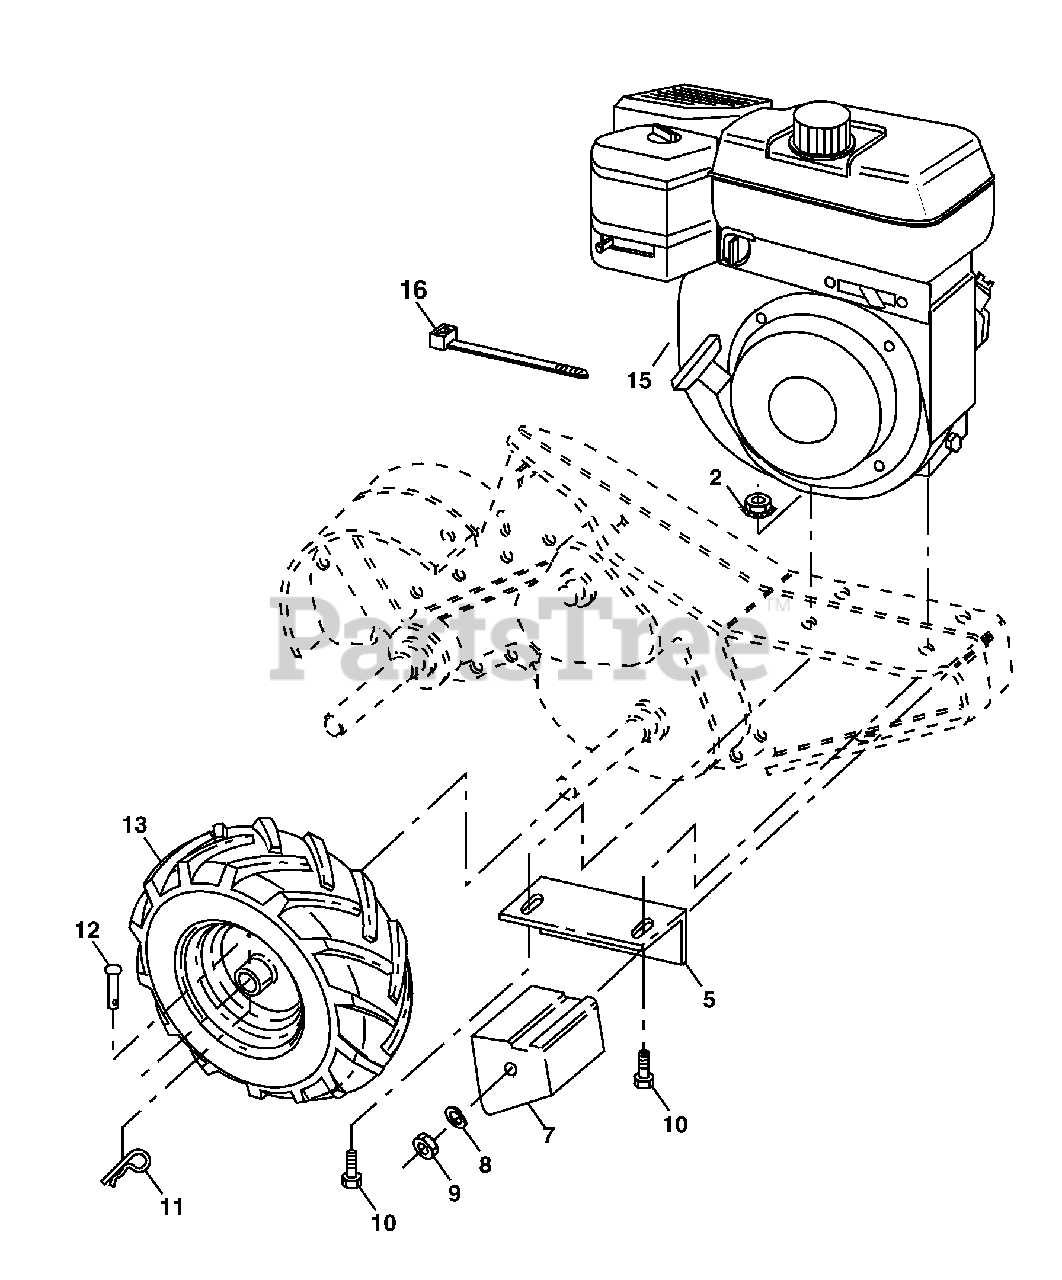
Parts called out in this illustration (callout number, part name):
2	Nut, Lock Hex Flange
5	Bracket, Reinforcement
7	Counter Weight, R.H.
8	Washer, Lock 3/8
9	Nut, Hex 3/8-16
10	Bolt, Hex 5/16-18 x 1-1/2
11	Clip, Hairpin
12	Rivet, Drilled
13	Tire
13	Rim
13	Tire Valve
16	Tie Cable
